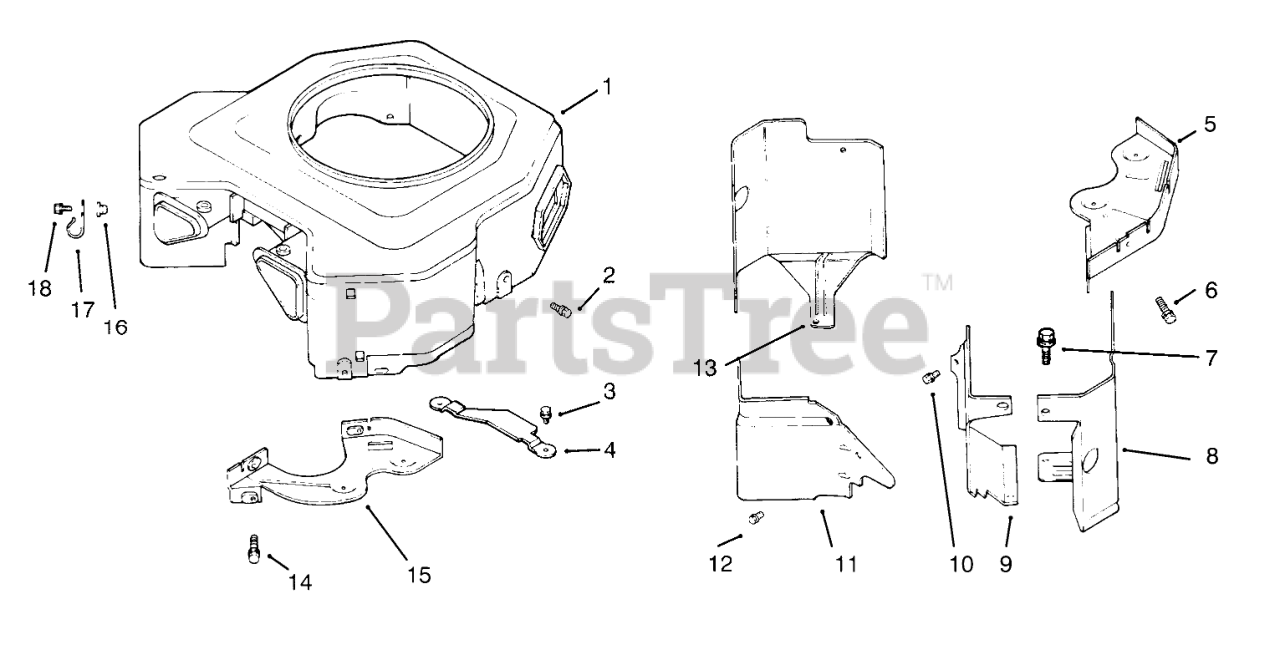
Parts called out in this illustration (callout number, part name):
1	Blower Housing ASM
3	Screw
4	Guard-Flywheel
5	Plate-Backing #2 Side
7	Screw
8	Baffle-Cylinder, #2
9	Baffle-Valley #1 Side
10	Screw
11	Baffle-Valley #2 Side
13	Baffle-Cylinder #1Side
14	Screw
15	Plate-Instruction
16	Nut
17	Clamp
18	Screw
